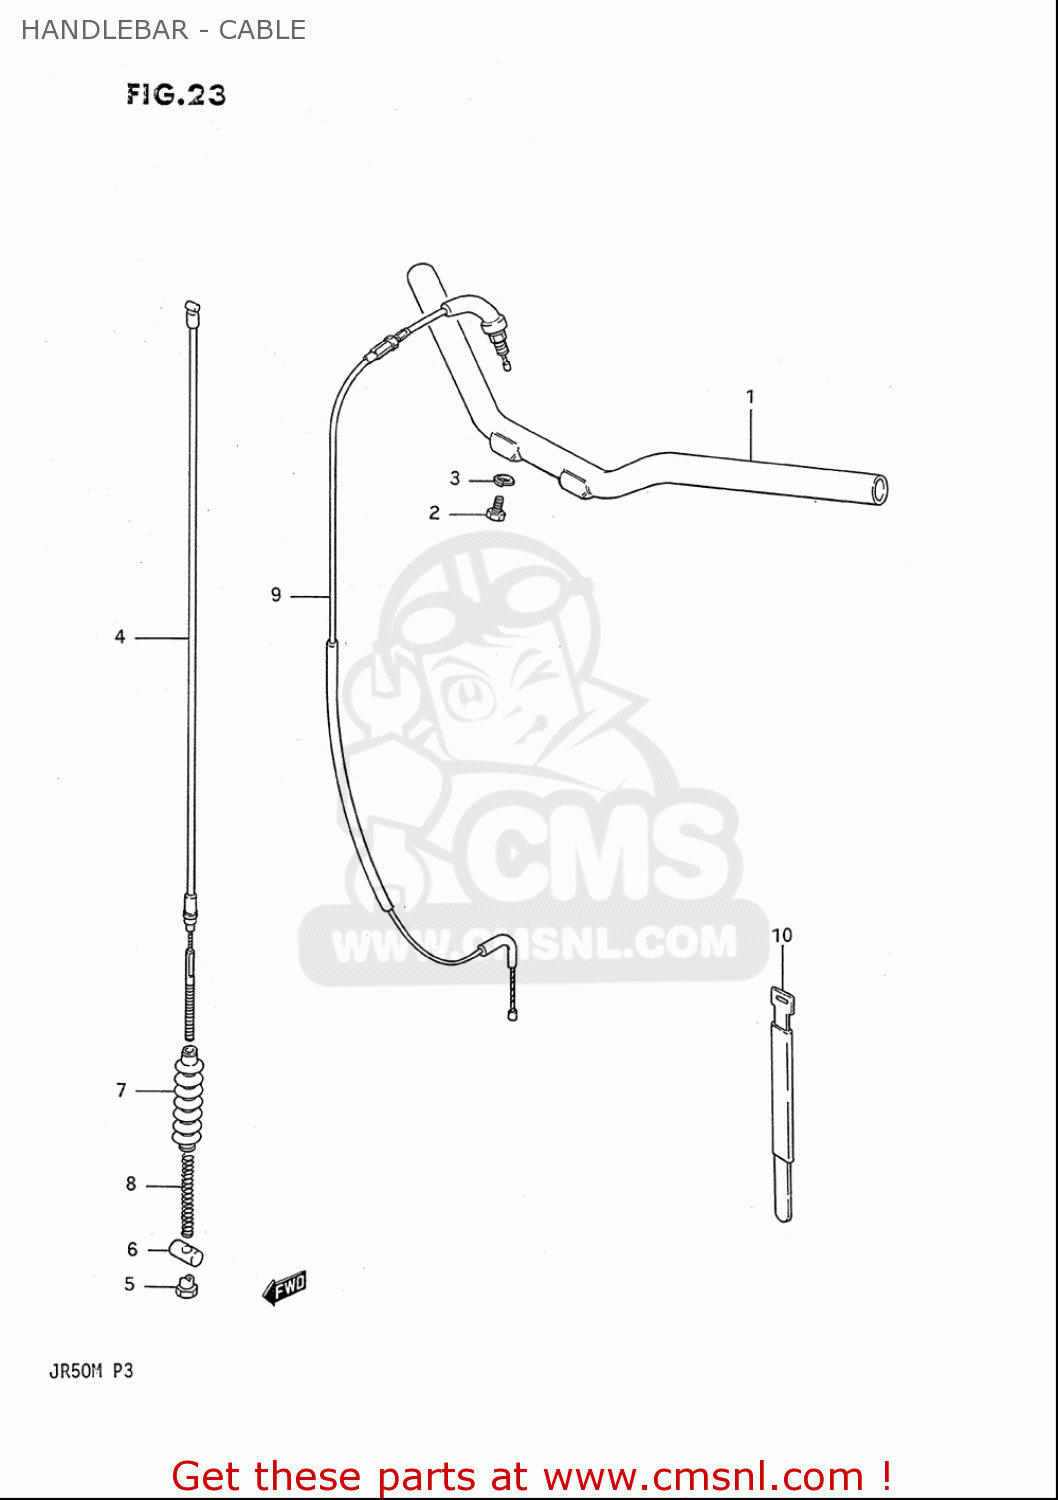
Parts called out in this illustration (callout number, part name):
1	HANDLEBAR
2	BOLT
3	WASHER,LOCK
4	CABLE,FR BRAKE
7	SEAL,DUST(7X16X75)
8	SPRING
9	CABLE ASSY,THROTTLE
10	CLAMP
